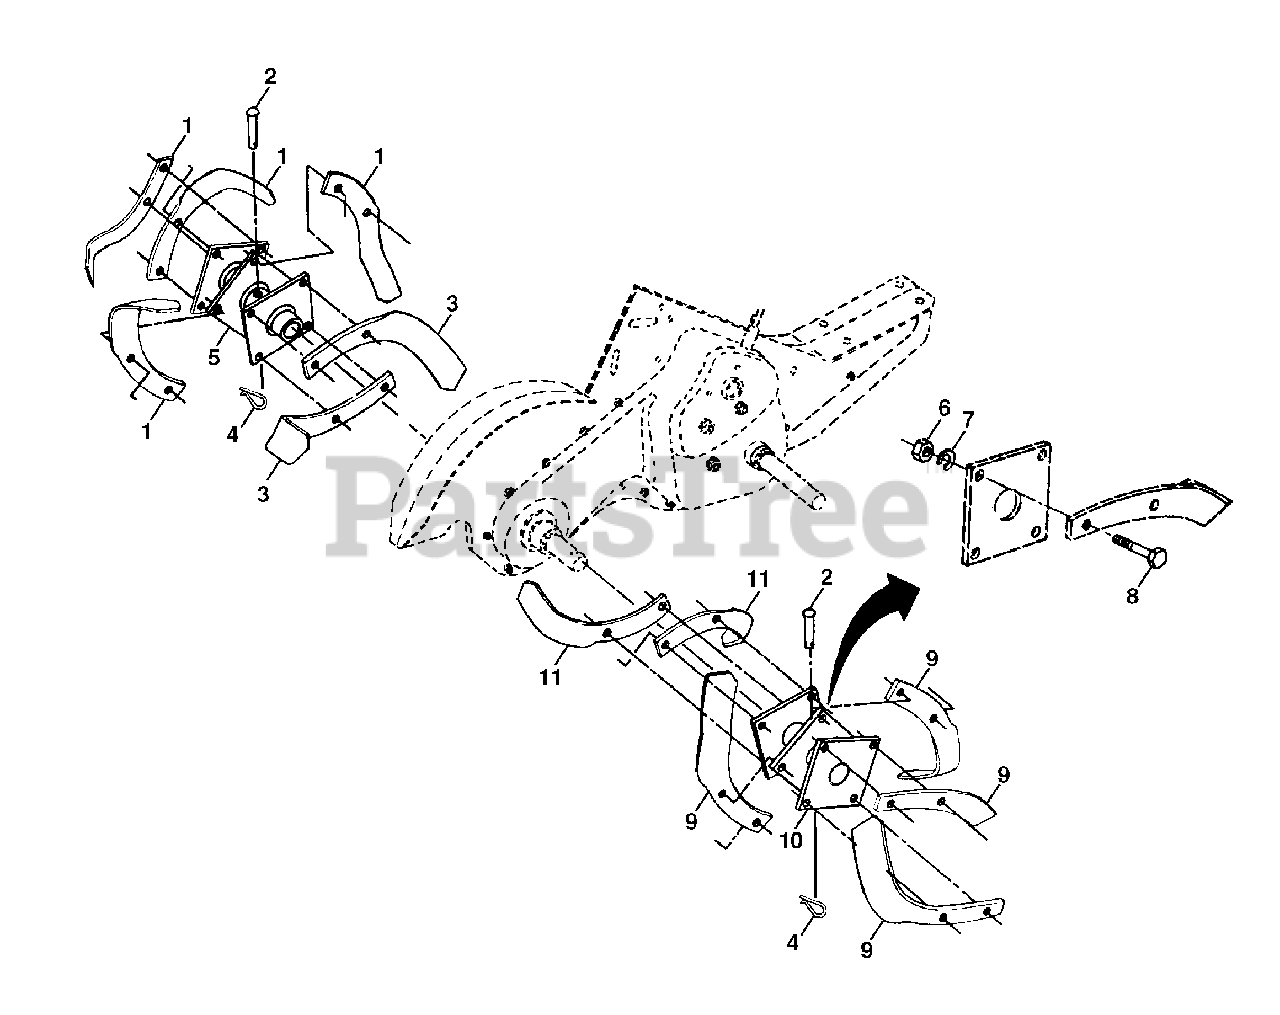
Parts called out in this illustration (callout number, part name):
1	Tine, Outer, L.H.
2	Clevis Pin
3	Tine, Inner, L.H.
4	Retainer, Spring
5	Assembly, Hub and Plate, L.H.
6	Nut, Hex 3/8-24
7	Washer, Lock 3/8
8	Bolt, Hex 3/8-24 x 1
9	Tine, Outer, R.H.
10	Assembly, Hub and Plate, R.H.
11	Tine, Inner, R.H.
